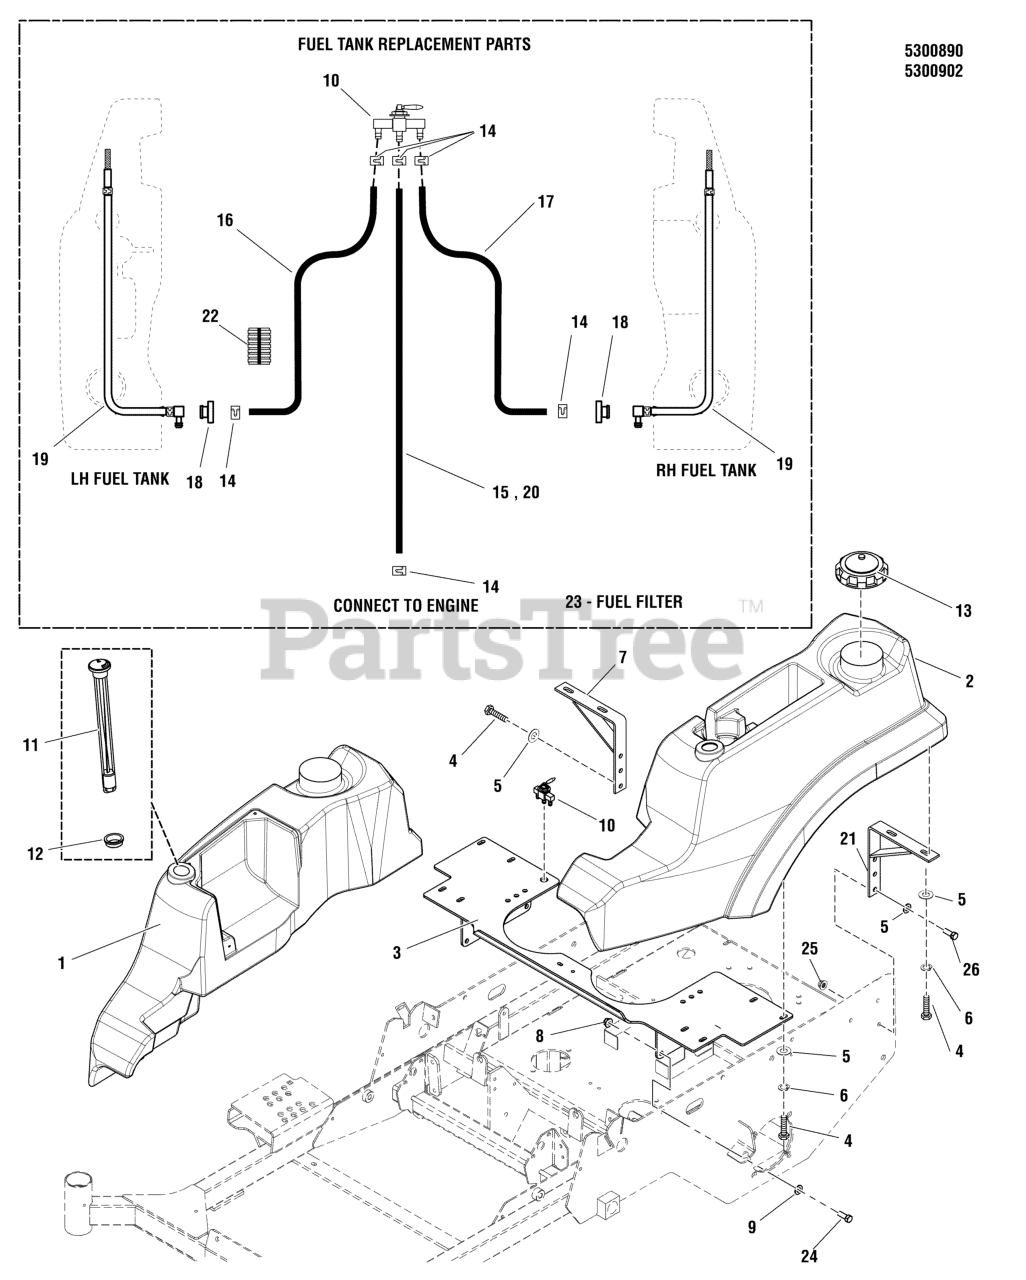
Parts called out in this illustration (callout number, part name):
1	TANK, FUEL, SNAPPER PRO - RH
2	TANK, FUEL, SNAPPER PRO - LH
3	WELD, TANK MOUNT - RED
4	BOLT, 5/16-18 X 3/4 GD5
5	WASHER, 5/16" SAE
6	WASHER, 5/16 LOCK CZ
7	WELD, TANK MOUNT, REAR, RH
8	NUT, 3/8-16 HEX NYLOCK FLANGE
9	WASHER, 3/8 SAE
10	VALVE, FUEL, STR. OUTLET
11	GAUGE, FUEL, 12
12	GROMMET, FUEL GUAGE (SV)
13	CAP, GASOLINE, VENTED
13	CAP, FUEL TANK, 3-1/2 NECK
14	CLAMP, HOSE, EXTERNAL, 1/2 - RED
15	HOSE, LW PRMTN, 1/4" FUEL, 23.00" (SV)
16	HOSE, LW PRMTN, 1/4" FUEL, 48.00" (SV)
17	HOSE, 1/4" FUEL, 28.00"
18	BUSHING-FUEL TANK RED RUBBER
19	PICKUP TUBE ASSEMBLY, FUEL LINE (SV)
20	HOSE, LW PRMTN, 1/4" FUEL, 12.00" (SV)
21	WELD, TANK MOUNT, REAR, LH
22	WIRE LOOM, 1/2 ID X 18.00" (SV)
23	FILTER, FUEL
24	BOLT, 3/8-16 X 1" GD5 CZ
25	NUT, 5/16-18 HEX NYLOCK FLANGE
26	BOLT, 5/16-18 X 1 GD5 YZ
